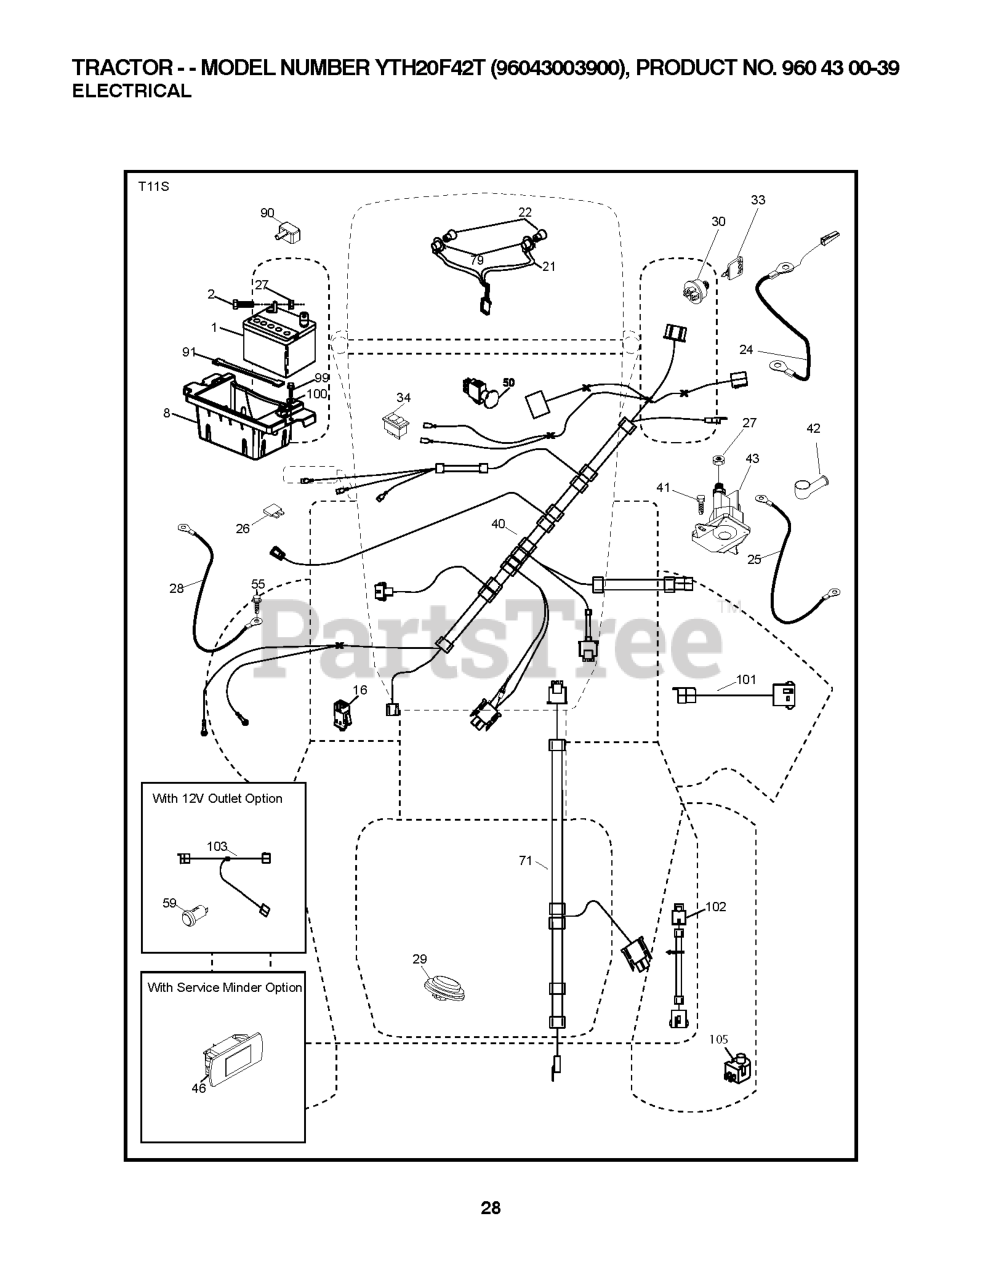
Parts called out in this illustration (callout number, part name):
1	Battery 12 Volt 25 Amp
2	BOLT.HEX.1/4.X.3/4.DICHROMATE
8	BOX.BATTERY.MOUNT.FRONT.LT
16	SWITCH INTERLOOK PUSH-IN
21	HARNESS ASSY LIGHT
24	CABLE.BATT.POS.WIRE.TG.DA SOL
25	CABLE.STARTER.6G.BL/RED.17.5
26	FUSE 20AMP
27	NUT
28	CABLE GROUND 6 GA 21" 90T BLK
29	SWITCH.SEAT.DELTA.OPC.
30	SWITCH.IGN.DELTA.W.LGH.ROS
33	KEY.CHAIN.BLISTER.PACK.GEN.INT
40	HARNESS.IGN.DASH.HUQ/P
41	SCREW
42	TERMINAL COVER
43	SOLENOID.W/BRASS.PLUNGER
46	RP.GUAGE.SRVCMNDR.HRMTR.
50	RP.PTO.SWITCH.8 TERMINAL.BLACK
55	SCREW 5/16"
71	HARNESS-CHASSIS SUB
79	BULB HOLDER ASM.
90	COVER.TERMINAL.BATTERY
91	STRAP.BATTERY.MOUNT.FRONT(2 2)
99	SCREW HEXWSHR 1/4-20X3/4
101	PIGTAIL.MATNLK.NEW.HAR
102	HARNESS PIGTAIL PCH TEX ROS
105	REVERSE SWITCH
